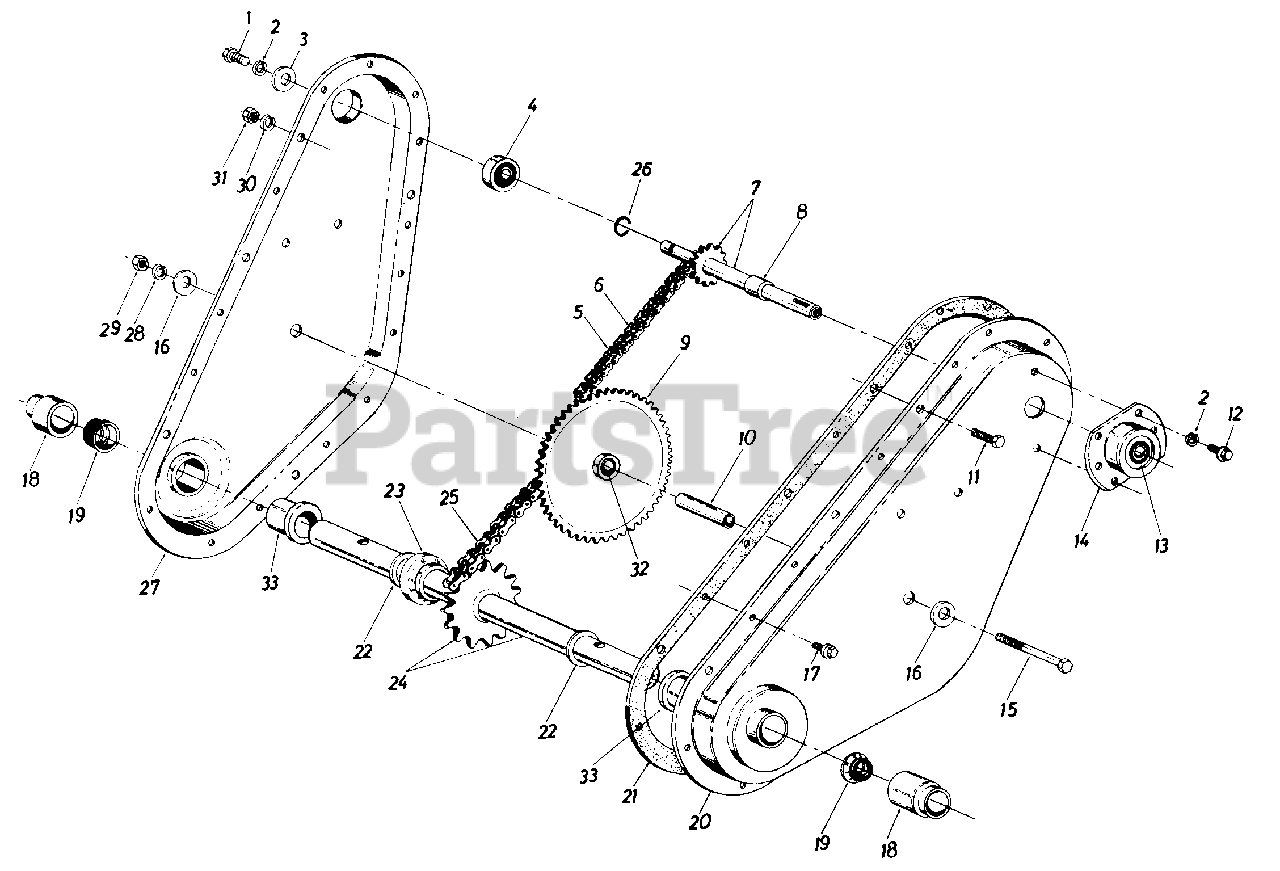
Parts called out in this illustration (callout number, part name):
1	Hex L-Scr. 1/4-28 x .625" Lg.
2	L-Wash. 1/4" I.D.
3	Fl-Wash. .25" I.D. x .93" O.D. x .125" Thk.
4	Bearing .62" I.D. x 1.38" O.D. x .437" Thk.
5	#35 Chain 3/8" Pitch x 52 Links Endless
6	Master Link
7	Input Shaft Assembly
8	Spacer
9	Sprocket Assembly
10	Sprocket Hub Tubing 3/8" I.D. x 5/8" O.D. x 1.9" Lg.
11	Hex Scr. 5/16-18 x .625" Lg.
12	Hex Wash. Hd. Self-Tap Scr. 1/4 -20 x .50" Lg.
13	Bearing .625" I.D. x 1.38" O.D. x .437" Thk.
14	Bearing Housing
15	Hex Scr. 3/8-24 x 2.75" Lg.
16	Fl-Wash. 3/8" I.D. x 1.25 O.D. x .100 Thk.
17	Hex Wash. Hd. Self-Tap Scr. 1/4-20 x .50" Lg.
18	Dust Cap
22	Thrust Wash. 1.00" I.D. x .030" Thk.
23	Step Spacer
24	Tine Shaft Assembly
25	#50 Chain 5/8" Pitch x 46Links Endless
26	Snap Ring
29	Hex Nut 3/8-24 Thd.
30	L-Wash. 5/16" Scr.
31	Hex Nut 5/16-18 Thd.
32	Bearing
33	Bearing
